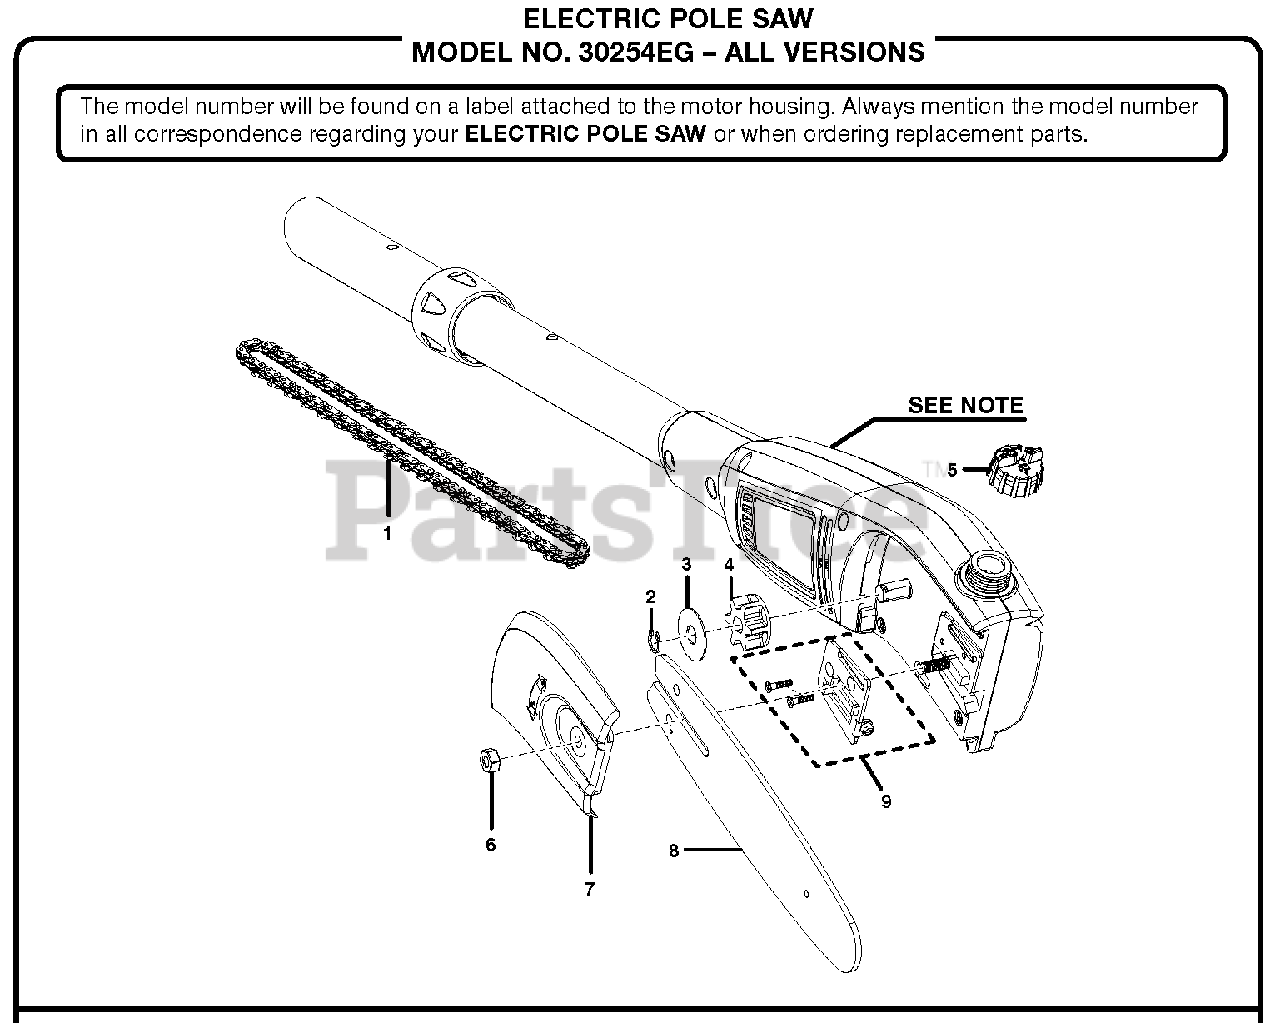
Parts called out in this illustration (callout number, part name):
2	Retaining Ring
4	Sprocket
6	Hex Nut (M6)
7	Chain Cover Assembly
9	Chain Adjustment Assembly
